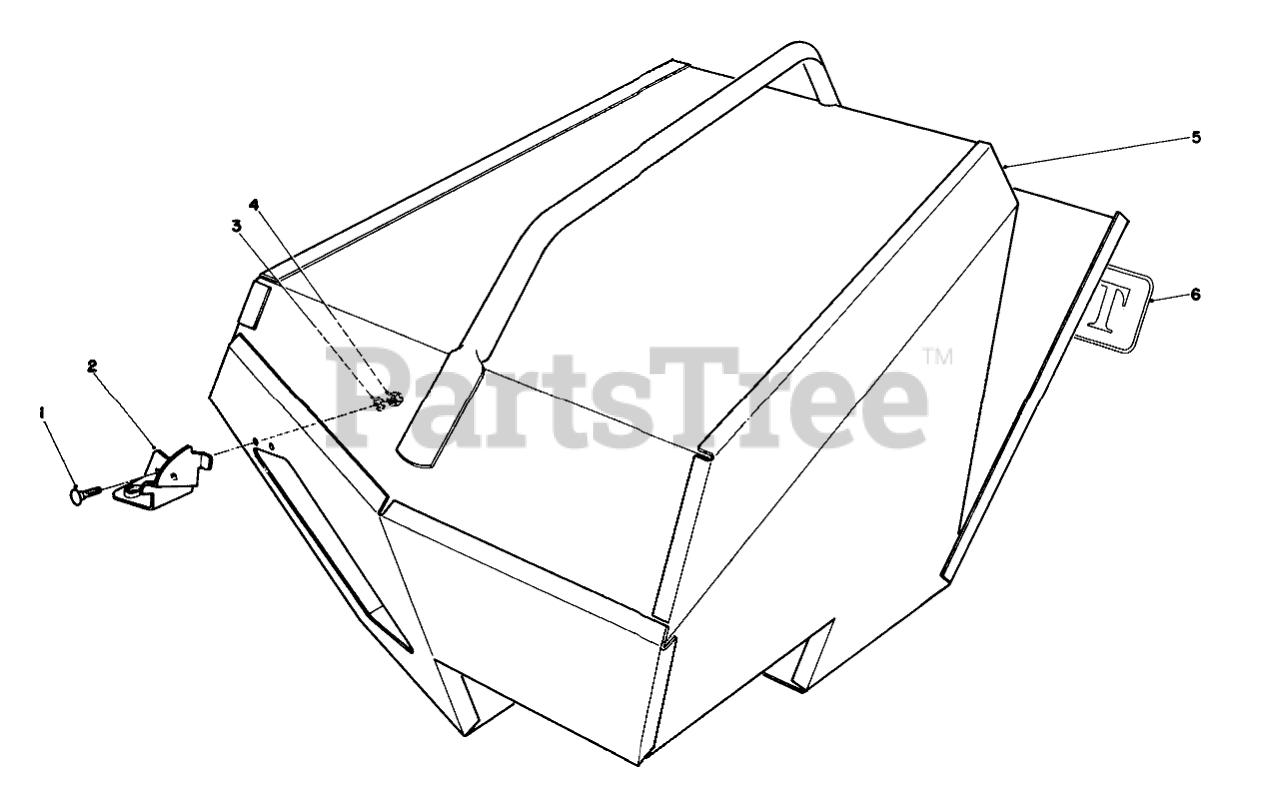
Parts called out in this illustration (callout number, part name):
1	SCREW-CARR
2	Bracket-Latch
3	WASHER-FLAT
4	NUT-LOCK, NI
5	Bag-Steel
6	Decal
